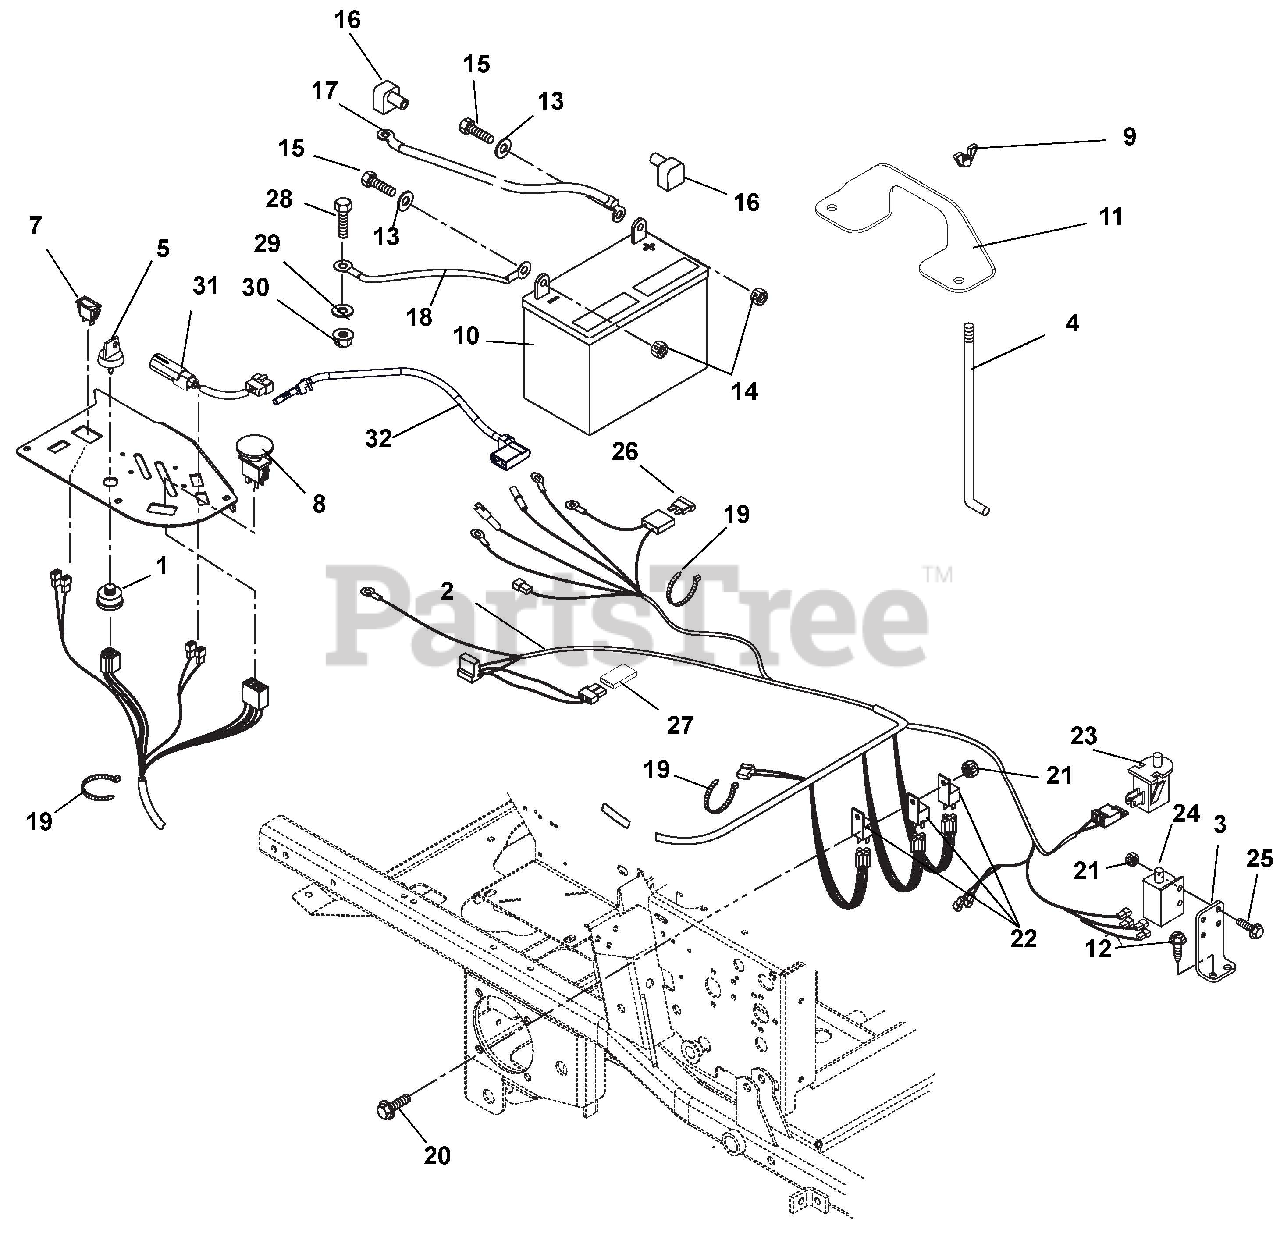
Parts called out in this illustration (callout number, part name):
1	Switch, Ignition
2	Harness, MZ Vertical A/C
3	Mount, Safety Switch
4	Rod, Battery Hold Down .25 x 6.62
5	Key, with Shield
6	Ignition Key Set
7	Hour Meter
8	Switch, PTO Clutch
9	Nut, Locking Wing .25-20
10	Battery, 12V
11	Hold Down, Battery
12	Screw, Tapping Hex Washer Head .25-20 x .50
13	Washer, Flat Steel .281 x .620 x .065
14	Nut, Hex .25-20
15	Bolt, Hex .25-20 x .75 Grade 5
16	Battery Terminal Boot, Red
17	Starter Cable 13"
18	Ground Cable
19	Cable Tie
20	Screw, Machine 10-24 x .50 Hex Washer Head
21	Nut, Locking Nyloc 10-24 With Insert
22	Relay
23	Switch, Snap Mounting
24	Switch, Double Pole N.O./N.O.
25	Screw, Machine 10-24 x .75 Hex Washer Head
26	Fuse, 20 Amp
26	Fuse, 15 Amp
26	Fuse, 10 Amp
27	Diode, Connector Shell
28	Bolt, Hex .31-18 x .75 Grade 5
29	Washer, Flat Steel .344 x .688 x .065
30	Nut, Locking Top Flange .31-18
31	Light, Indicator
32	Lead, Starter Solenoid
